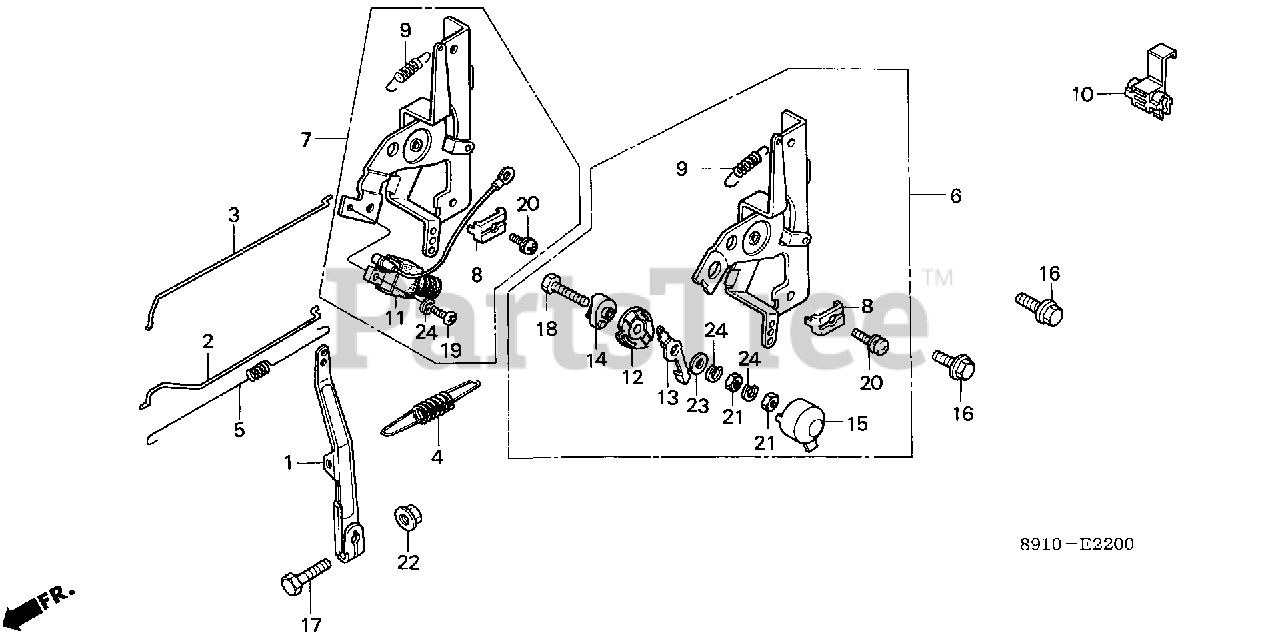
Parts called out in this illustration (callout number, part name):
1	ARM, GOVERNOR (NOT AVAILABLE)
2	ROD, GOVERNOR
3	ROD, CHOKE
4	SPRING, GOVERNOR
5	SPRING, THROTTLE RETURN (NOT AVAILABLE)
6	CONTROL ASSY.
8	HOLDER, CABLE
9	SPRING, CABLE RETURN
10	CONNECTOR, WIRE
12	BASE, SWITCH
13	CONTACT, SWITCH
14	WASHER, INSULATOR
16	BOLT, FLANGE (6X16)
17	BOLT, GOVERNOR ARM
18	BOLT, HEX. (4X20)
20	SCREW-WASHER (5X16)
21	NUT, HEX. (4MM)
22	NUT, FLANGE (6MM)
23	WASHER, PLAIN (4MM)
24	WASHER, SPRING (4MM)
